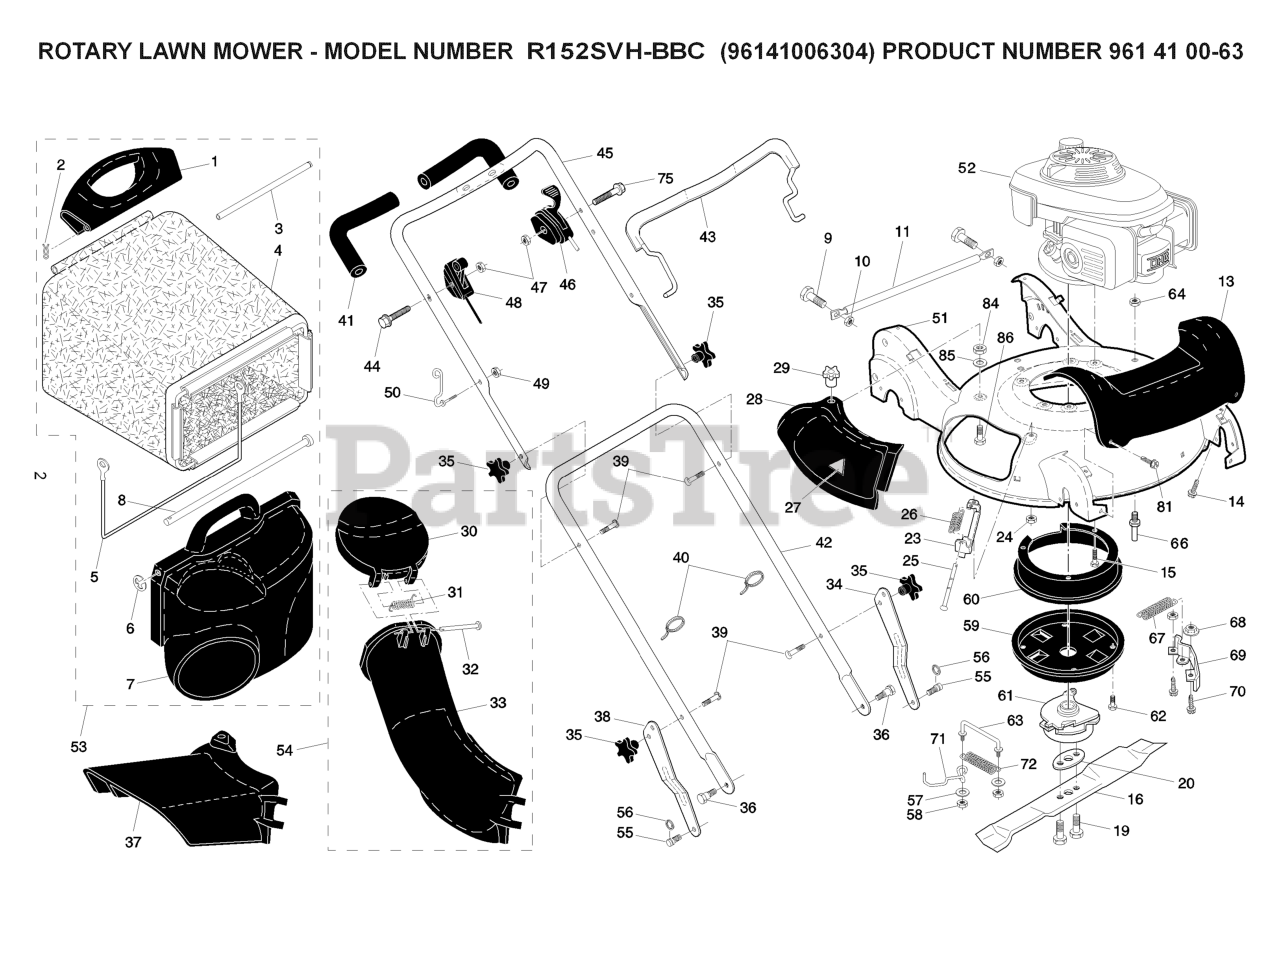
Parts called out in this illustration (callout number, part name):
1	HANDLE.GRASSBAG.REAR.H-GRAY
2	COTTER PIN (3 2)(2 2MC)
3	ROD.REAR.HANDLE.YELLOW
5	FRAME, GRASSBAG
7	DOOR, GRASSBAG
8	ROD, PIVOT
10	LOCKNUT.NYLOC.1/4-20
11	TUBE, REAR SKIRT
13	COVER.FRONT.21.HV.H-GRAY
14	SCREW, HEX WASHER HEAD
15	BOLT 3/8-16X1-1/8
23	BRACKET.ASM.HINGE
24	NUT.HEX.FLANGE.1/4
25	ROD.HINGE.1/4"3.82"
26	SPRING.MULCH.DOOR
27	DECAL.INTERNATIONL.CUTFINGER
28	MULCHER DOOR
29	KNOB.MULCH.DOOR
30	CHUTE.DOOR.21.HV.H-GRAY
32	ROD.HINGE.1/4"3.82"
33	DISCHARGE CHUTE PLASTIC
34	ADJUSTMENT BRACKET, LOWER LH
35	KNOB.HANDLE.STAR.HUSQ.GRAY
36	SCREW.5/16X.680.TRIM.H
37	GUARD.CLIP.ON.21.HV.GRAY
38	BRACKET.ADJ.LOWER.HDL.RT.GREY
39	BOLT, HANDLE 5/16-18X1.75
40	TIE GUIDE
41	GRIP.HANDLE.FOAM.WIDE.(1 SIDE)
42	HANDLE.LOWER.GREY
43	BAIL
45	HANDLE.ASM.UPPER.W/GRIP
46	CONTROL.BBC.HV.GRY/ORG
47	NUT
48	THROTTLE CONTROL
49	NUT
50	GUIDE.ROPE.WALK.MOWER
53	Grassbag Assembly, Complete
54	CHUTE.LOWER.ASM.WALK.MOWER
55	STUD.SHOULDER.T45.BZP
56	E-RING 7/16 RE
59	BELT COVER, LOWER
60	COVER.BELT.BBC.AW.TOP
62	TAPPING SCREW
63	LINK.TORQUE.BBC
66	STUC.GUIDE.BELT.RWGD
67	SPRING.BBC
68	NUT T
69	BRAKE, CLUTCH
70	BOLT
71	BELT KEEPER
72	SPRING.LINK.BBC
81	SCREW.HWH.13-16-5.8.BZP
84	NUT, HEX
85	LOCKWASHER
86	BOLT.CARRIAGE.1/4-20 X 7/8
